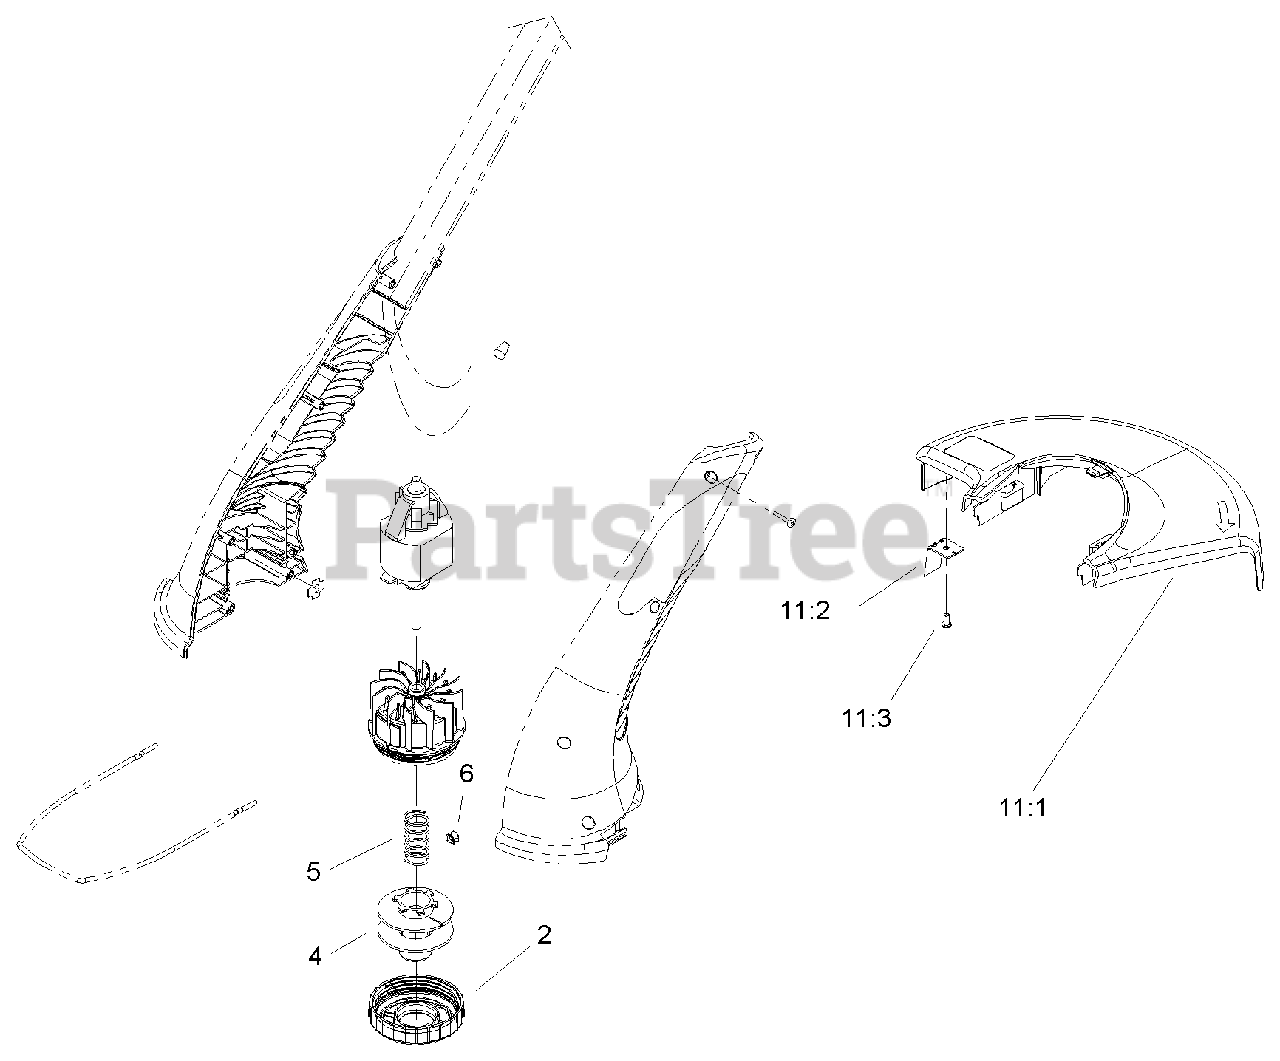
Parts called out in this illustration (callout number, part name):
4	.065 SPOOL ASM
5	Spring-Extension
6	EYELET-GUIDE
11:1	SHEILD-12 INCH
11:2	Blade-Cutoff
11:3	Screw-PPH
